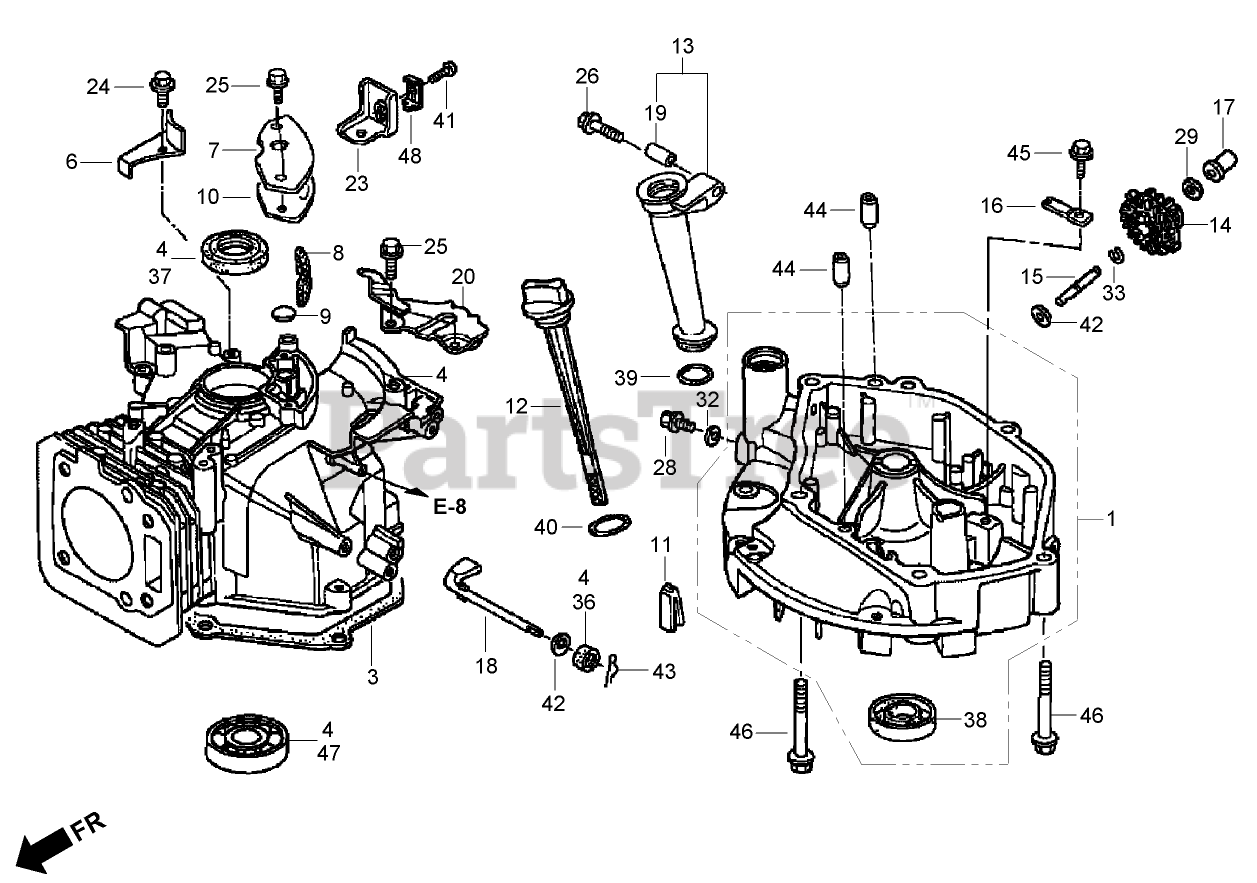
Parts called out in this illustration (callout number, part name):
1	OIL PAN ASM
3	GASKET-PAN, OIL
4	CYLINDER ASM
6	GUIDE-PLATE, A
7	COVER-BREATHER
8	Filter-Breather
9	VALVE-BREATHER
10	GASKET-COVER, BREATHER
11	RUBBER-RETURN, OIL
12	Dipstick-Oil
13	EXTENSION-FILLER, OIL (106 mm)
14	GOVERNOR ASM
15	SHAFT-HOLDER, GOVERNOR
16	Plate-HOLDER, Governor Shaft
17	SLIDER-GOVERNOR
18	SHAFT-ARM, GOVERNOR
19	Collar-Extension
20	STAY-TANK
23	BASE-HOLDER
24	BOLT-FLANGE (6X12) (C T200)
25	BOLT-FLANGE (6X14) (C T200)
26	Bolt-Flange (6X32)
28	Bolt-PLUG, Drain
29	WASHER-THRUST (6MM)
32	WASHER-PLUG, DRAIN (102MM)
33	CLIP-HOLDER, GOVERNOR
36	SEAL-OIL (6X11X4)
37	SEAL-OIL (25X38X7)
38	SEAL-OIL (25.4X40X7)
39	O-RING (22.1X2.2)
40	O-RING (25.5X3)
41	Screw-Pan (5X16)
42	WASHER-PLAIN (6MM)
43	PIN-LOCK (8MM)
44	Pin-Dowel (8X14)
45	Bolt-Flange (6X12)
46	BOLT-FLANGE (8X50)
47	BEARING-BALL, RADIAL (6205)
48	Holder-Cable
